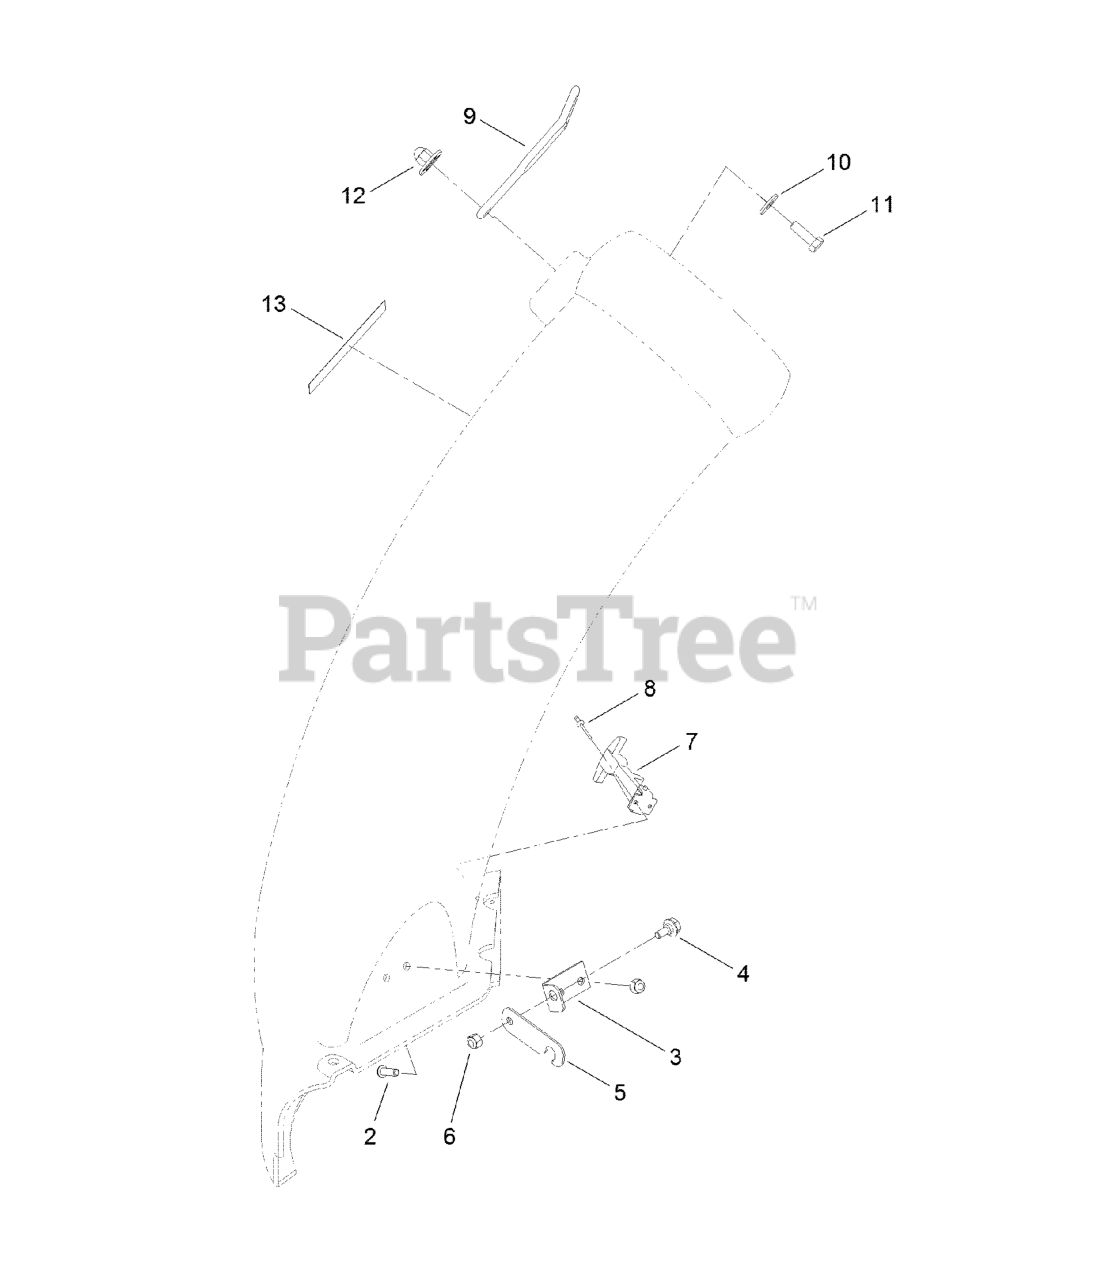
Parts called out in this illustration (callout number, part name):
2	SCREW-HSBH
3	PLATE-PIVOT
4	SCREW-SHOULDER,HWH
6	NUT-LOCK, NI
7	HANDLE ASM
8	RIVET-POP
9	RETAINER-DUCT
10	WASHER-FLAT
11	SCREW-HH
12	NUT-IMPELLER
13	DECAL-DANGER
